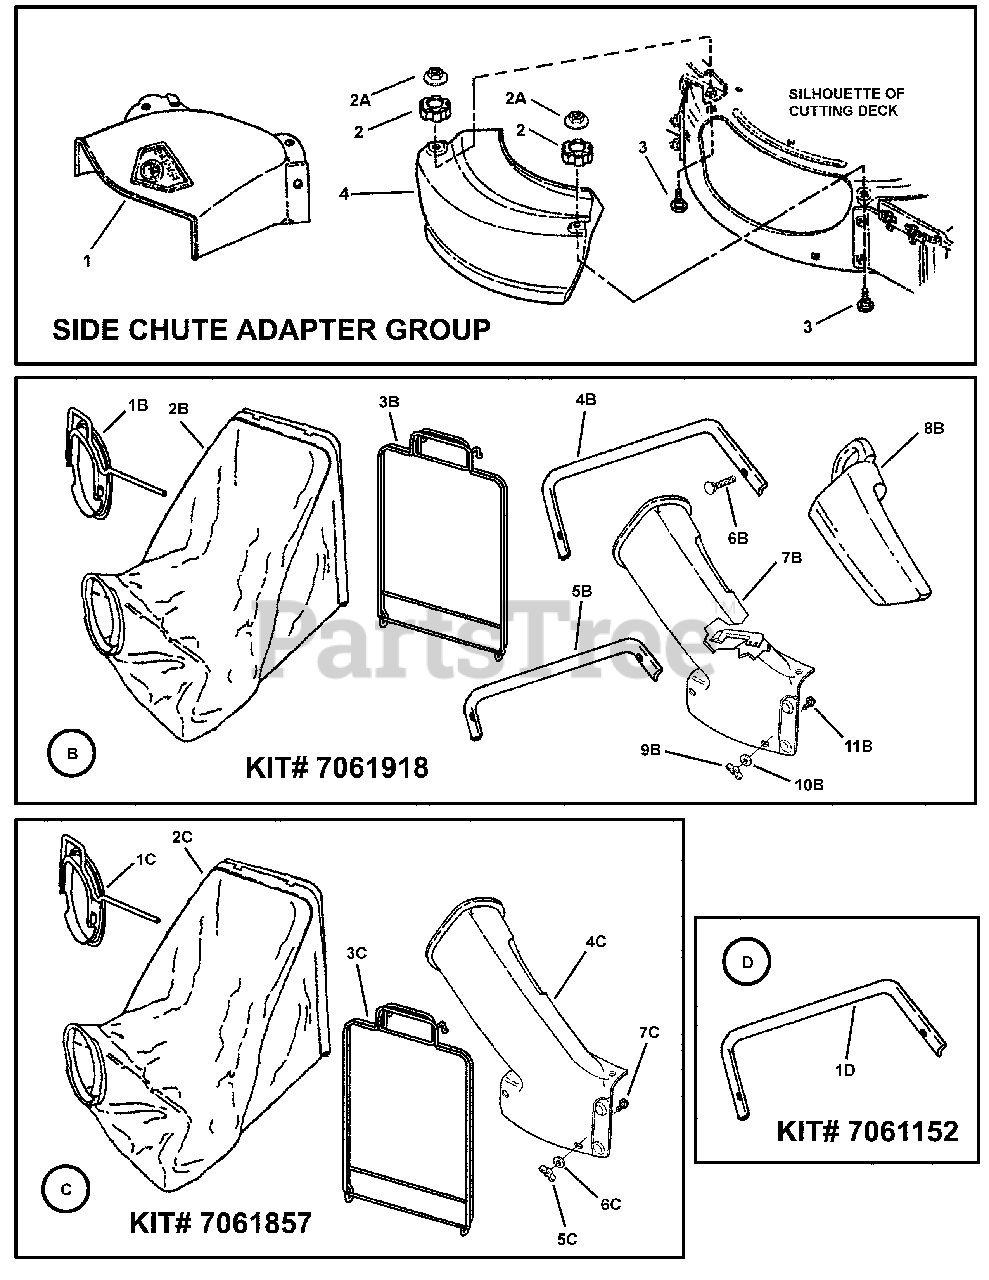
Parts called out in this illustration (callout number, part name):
1	CHUTE, 19" Side w/o interlock tab
1B	CONNECTOR, Bag
1C	CONNECTOR, Bag
1D	BAR, Cross
2	KNOB, Fluted, 5/16-18 Thread (yellow)
2	KNOB, Fluted, 5/16-18 Thread
2A	NUT, 5/16-18 Large Flange Center Lock
2B	BAG, Grass (13" wide)
2C	BAG, Grass (13" wide)
3	BOLT, 5/16-18 x 3/4" Short Neck Carriag, GR 5
3B	ASSEMBLY, Bag Wire (13" wide)
3C	ASSEMBLY, Bag Wire (13" wide)
4	COVER, Recycling, 19"/20"
4B	BAR, Cross
4C	ADAPTER, 19" Deck
5B	STIFFENER, Upper
5C	WING NUT, 5/16-18 thread w/Nylon Ring
6B	BOLT, 5/16-18 x 2" Curved Head Square Neck, GR 2
6C	WASHER, 5/16" Flat
7B	ASSEMBLY, Bag Adapter
7C	BOLT, 5/16-18 x 3/4" Short Neck Carriage, GR 5
8B	PLUG, Chute Adapter
9B	WING NUT, 5/16-18 thread w/Nylon Ring
10B	WASHER, 5/16" Flat
11B	BOLT, 5/16-18 x 3/4" Short Neck Carriage, GR 5
B	KIT, Bag "N" Plug (Grass Catcher and Plug)
C	KIT, Grass Catcher (13" Wide)
D	KIT, Cross Bar (for attaching bag)
